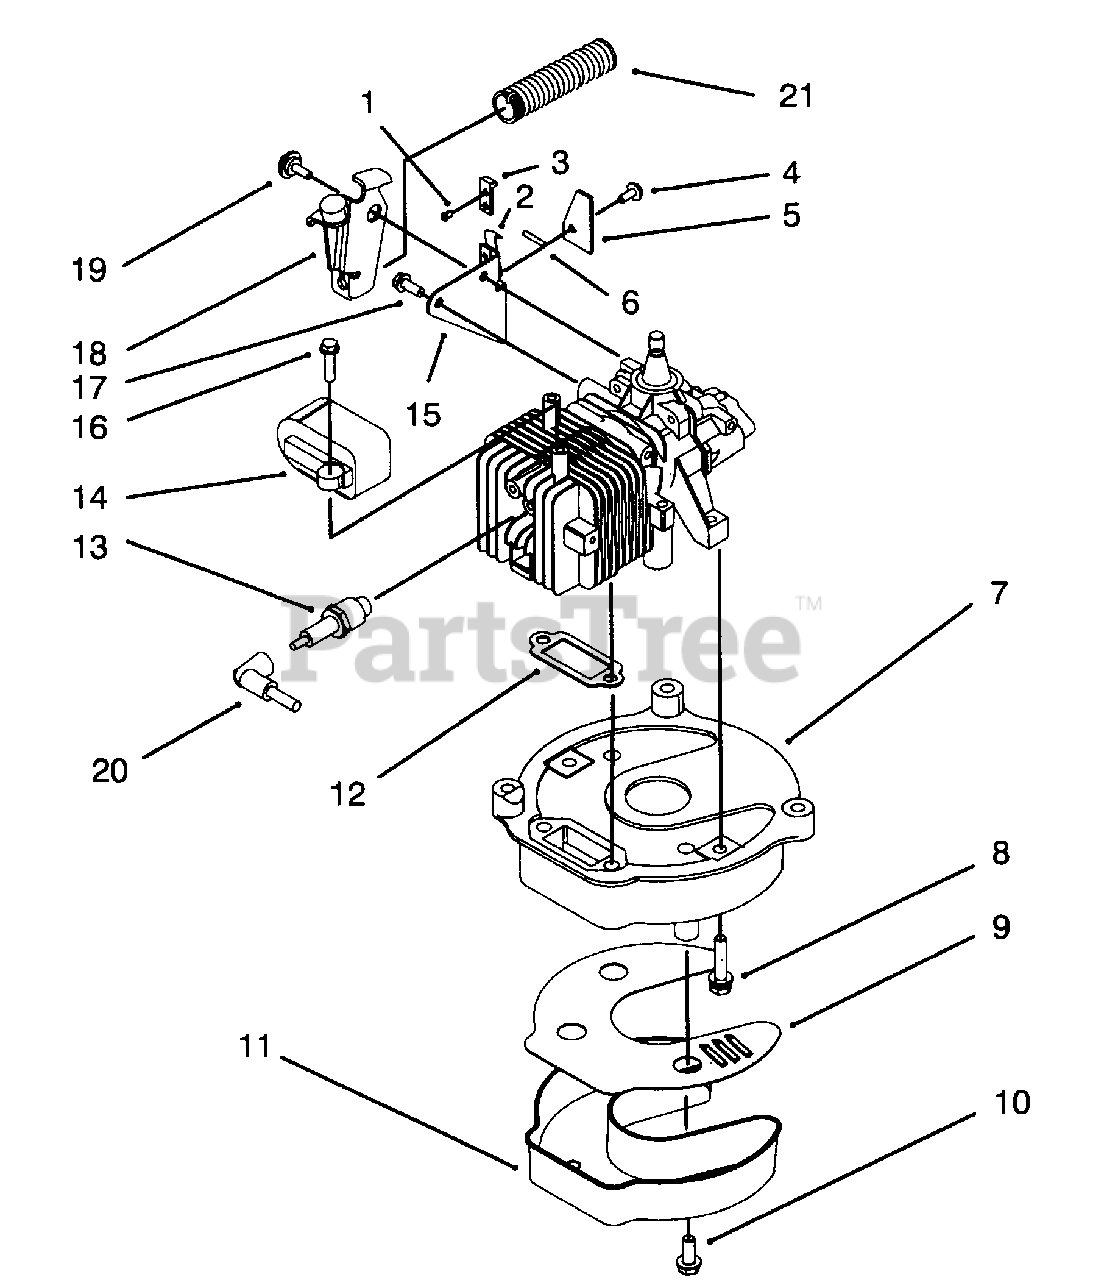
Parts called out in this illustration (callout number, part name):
2	Strap-Ground
3	Strap-Insulation
4	Screw-Thread Forming
5	Stop-Ground Strap
6	Wire-Brake Switch Lead
7	Plate-Muffler
9	Baffle
11	Cover-Muffler
12	Gasket-Exhaust
13	Plug-Spark
14	Ignition Assembly (Incl. Ref.#20)
15	Plate-Brake Mount
16	Screw-Hex Washer Hd.
17	Screw
18	Plate-Brake Assembly
19	Screw-Shoulder
20	Lead & Cover Assembly
21	Spring-Compression
